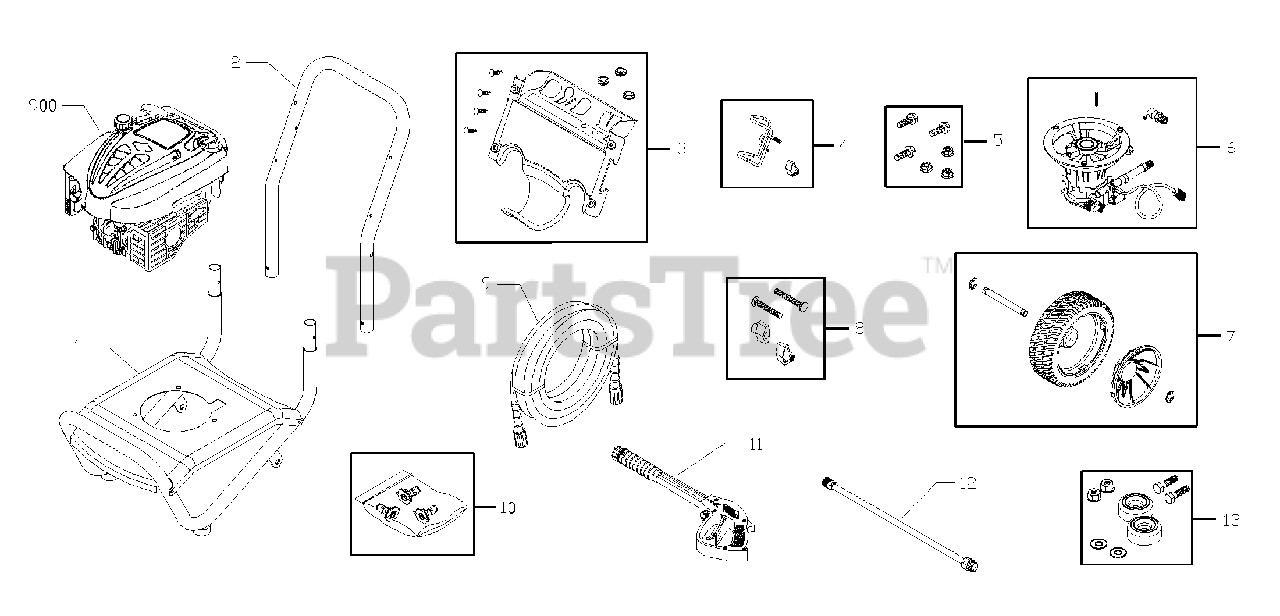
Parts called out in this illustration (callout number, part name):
2	HANDLE
3	KIT, Billboard w/Clips & Decals
4	KIT, Gun Holder
5	KIT, Pump Mounting Hardware
7	KIT, Wheel
8	KIT, Handle Connector
9	HOSE
11	GUN
12	EXTENSION
13	KIT, Vibration Mount
900	* ENGINE
